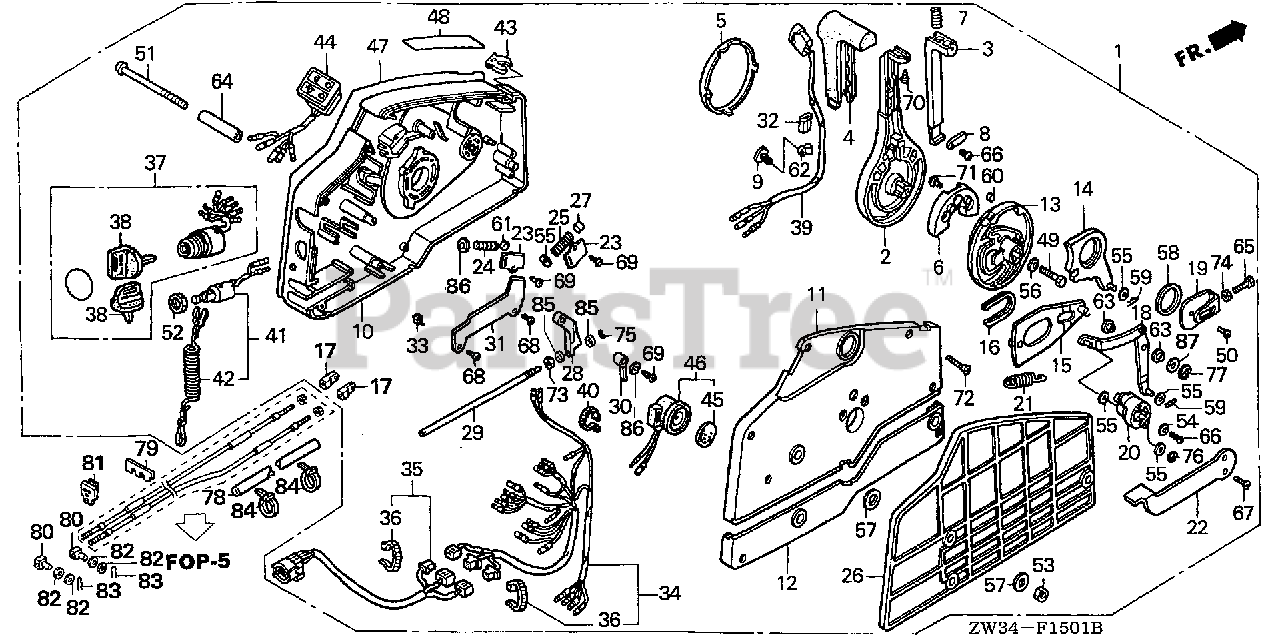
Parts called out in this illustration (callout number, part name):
1	S/R SW 2 LIGH POW TL
1	BOX ASSY., REMOTE CONTROL (P/T)
1	BOX ASSY., REMOTE CONTROL (P/T)(HI-LEX)
2	HANDLE, REMOTE CONTROL
3	LEVER, HANDLE LOCK
4	GRIP, REMOTE CONTROL HANDLE
5	CAP, HANDLE
6	BLOCK, NEUTRAL LOCK
7	SPRING, REMOTE CONTROL HANDLE
8	PLATE, LEVER SETTING
9	CLAMP, HARNESS
10	HOUSING, REMOTE CONTROL BOX (A)
11	HOUSING, REMOTE CONTROL BOX (B)
12	HOUSING, REMOTE CONTROL BOX (C)
13	WHEEL, CONTROL
14	ARM, SHIFT LINK
15	PLATE, SLIDING
16	COLLAR, SLIDING PLATE
17	PIVOT, SHIFT
18	ARM, LINK JOINT
19	BRACKET, LINK JOINT
20	WHEEL, ACCELERATOR
21	SPRING, ACCELERATOR WHEEL
22	LEVER, IDLE
23	PLATE, SPRING SETTING
24	SPRING, SHIFT CLICK
25	SPRING, CHOKE RETURN
26	SPACER, REMOTE CONTROL BOX
27	SPACER, CLICK SPRING
28	BLOCK, THROTTLE FRICTION
29	BOLT, FRICTION
30	SPACER, NEUTRAL SWITCH
31	CLAMP, POWER TILT CORD
32	PIPE, HARNESS GUIDE
33	SPACER, CABLE CLAMP
34	CABLE ASSY., REMOTE CONTROL (B)
35	CABLE ASSY., SWITCH PANEL
36	TIE, CABLE (2.4X92) (NATURAL)
37	SWITCH ASSY., COMBINATION
38	KEY ASSY., COMBINATION SWITCH (35100-ZV5-003 ONLY)
39	SWITCH ASSY., POWER TRIM-TILT
40	BAND (BLACK 3.5X140)
41	SWITCH ASSY., EMERGENCY STOP
42	WIRE, EMERGENCY
43	CLIP, EMERGENCY LOCK
44	LAMP ASSY., INDICATION (2-LED)
45	PLATE, TURN SIGNAL BUZZER
46	BUZZER, WARNING
47	PLATE, REMOTE CONTROL (CAUTION PICT=SILVER)
48	MARK, FAST IDLE
49	BOLT, HEX. (8X35)
50	SCREW, PAN (6X10)
51	SCREW (6X95)
52	NUT, HEX. (16MM)
53	NUT, HEX. (6MM)
54	WASHER, PLAIN (5MM)
55	WASHER, PLAIN (6MM)
56	WASHER, PLAIN (8MM)
57	WASHER (6MM)
58	WASHER (28MM)
59	PIN, LOCK (6MM)
60	PIN (6X6)
61	ROLLER, CLICK
62	CLIP, WIRE HARNESS (6.3MM)
63	COLLAR, LINK JOINT
64	COLLAR, DISTANCE (6X10X43.5)
65	BOLT, HEX. (5X16)
66	SCREW, PAN (5X10)
67	SCREW, OVAL (5X12)
68	SCREW, TAPPING (5X8)
69	SCREW, TAPPING (5X10)
70	SCREW, TAPPING (5X12)
71	SCREW, TAPPING (6X16)
72	SCREW, TAPPING (5X25)
73	NUT, HEX. (6MM)
74	NUT, HEX. (5MM)
75	E-RING (3MM)
76	E-RING (4MM)
77	E-RING (7MM)
78	TUBE, CORRUGATE (28MM)
79	PLATE, REMOTE CONTROL CABLE
80	PIVOT, SHIFT
81	GROMMET, CASE (LOWER) (A)
82	WASHER, PLAIN (6MM)
83	PIN, SPECIAL LOCK (6MM)
84	BAND, SELF-LOCK
85	WASHER, PLAIN (4MM)
86	WASHER, PLAIN (5MM)
87	WASHER, PLAIN (8MM)
